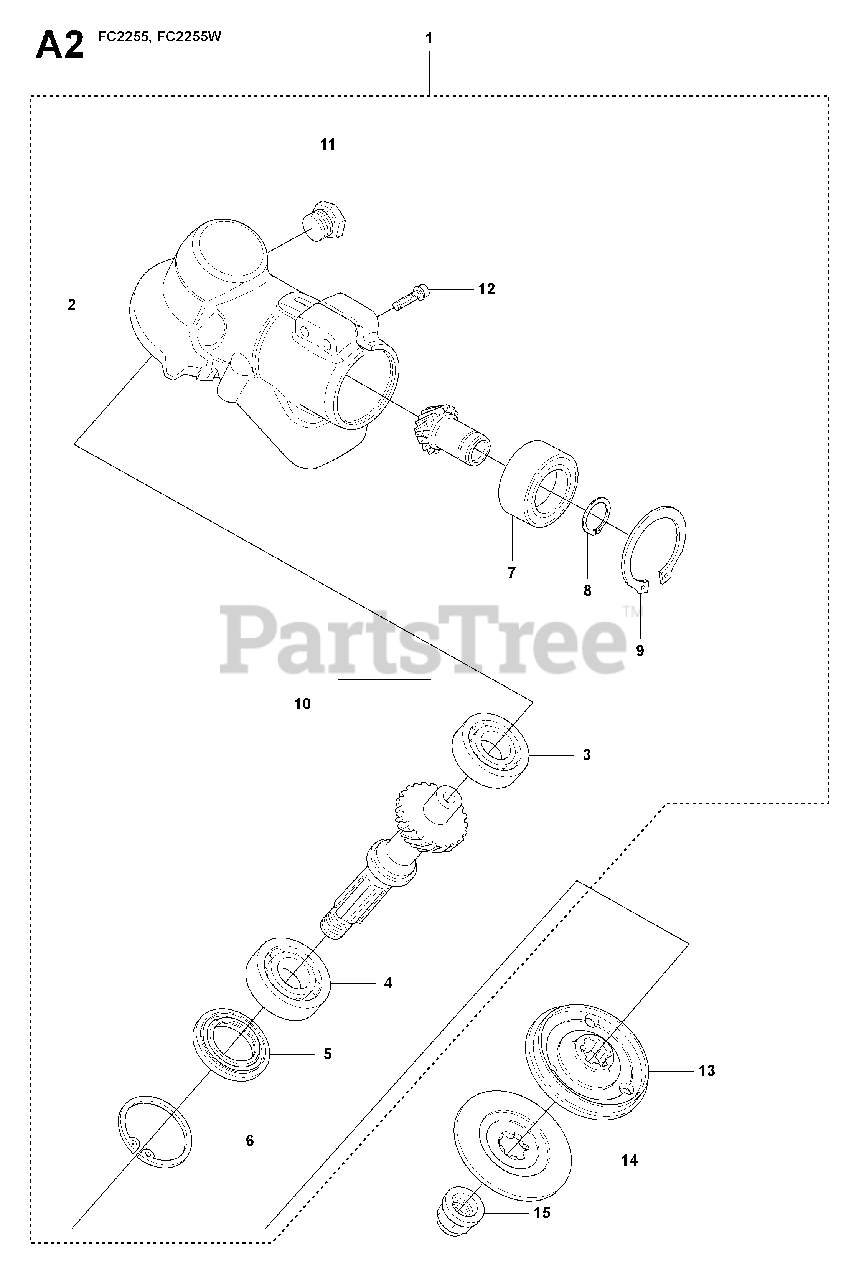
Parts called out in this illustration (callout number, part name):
1	RP BEVEL GEAR
2	%GEAR HOUSING
3	BALL BEARING
4	BALL BEARING
6	RETAINING RING SGH 35
8	RETAINING RING SGA 15
9	RETAINING RING
10	BEVEL GEAR
14	SUPPORT FLANGE
15	BLADE NUT
